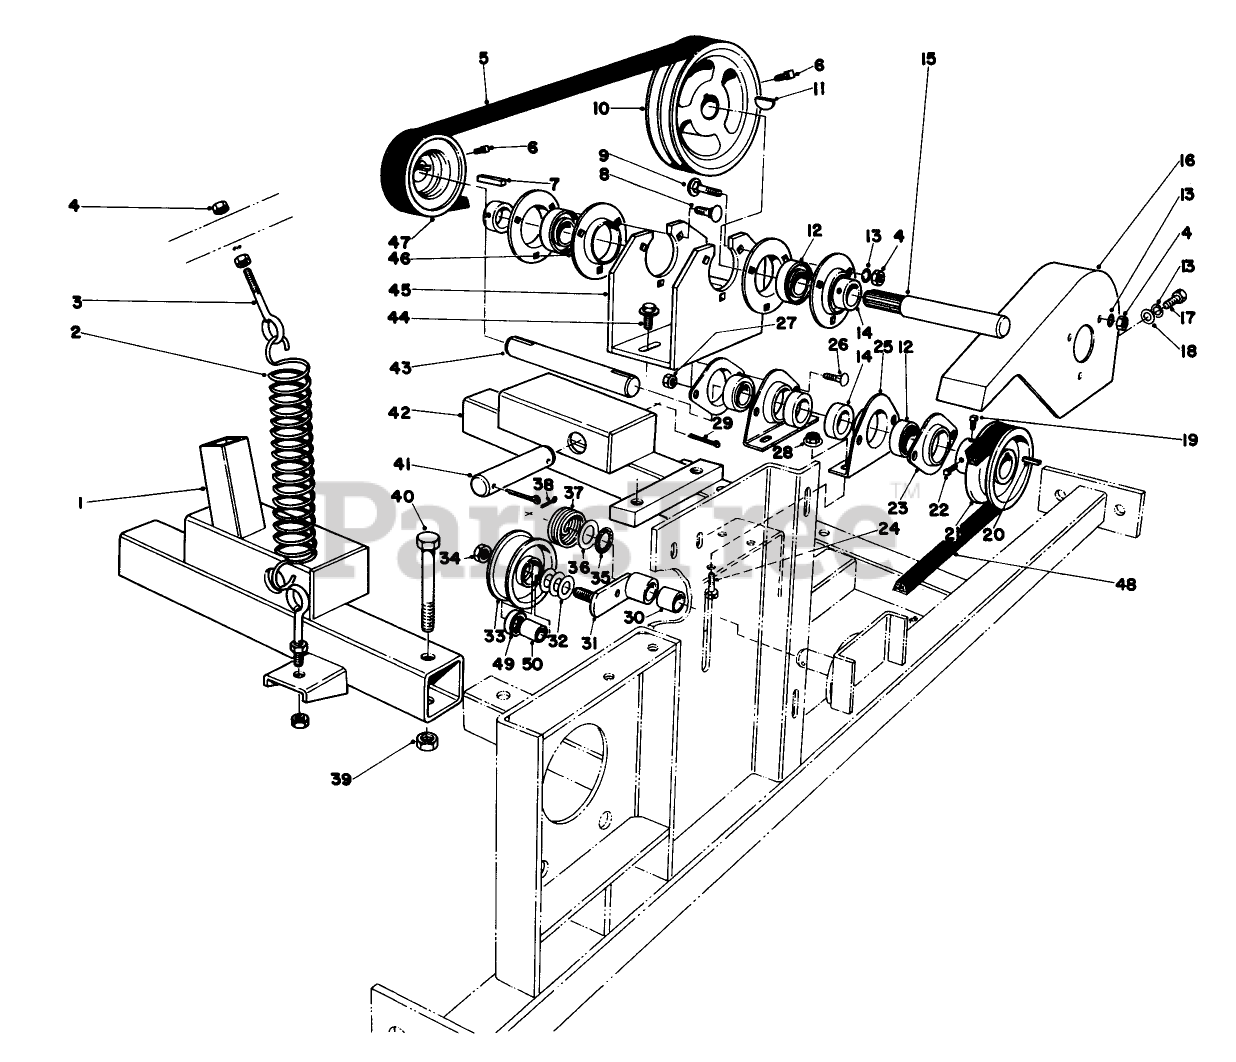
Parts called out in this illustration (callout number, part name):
1	Adapter R.H.
2	Extension Spring
3	Eyebolt
4	NUT-HEX
5	V-BELT
6	SCREW-SET, SQH
8	SCREW-CARR
9	BOLT-CARR
10	JACKSHAFT PULLEY
11	KEY-WOODRUFF
12	Bearing (Incl. Ref. #14)
13	WASHER-LOCK/SP
14	COLLAR-LOCK, BEARING
15	JACKSHAFT
16	Belt Shield
17	SCREW-HH
18	WASHER-PLAIN
19	5/16-18 X 1/2 SQ HD
21	SHEAVE 60103
22	SCREW-SQH
23	Flange
24	SCREW-HH
25	FLANGE
26	BOLT-CARR
27	NUT-HF
28	NUT-HHF, WHIZ
29	3/32 X 1-3/4 LG COTTER
30	BUSHING 16162
31	Idler Arm (Incl.Ref.#30)
32	WASHER-FLAT
33	Idler Pulley
34	LOCKNUT 6239
35	Felt Washer
36	Washer
37	Spring-Torsion
38	PIN-COTTER
39	NUT-LOCK, CONE
40	SCREW-HH
42	Adapter L.H.
43	JACKSHAFT
44	SCREW-HHF
45	JACKSHAFT SUPPORT
46	FLANGE
47	JACKSHAFT PULLEY
48	V-BELT
49	Bearing
50	Sleeve
